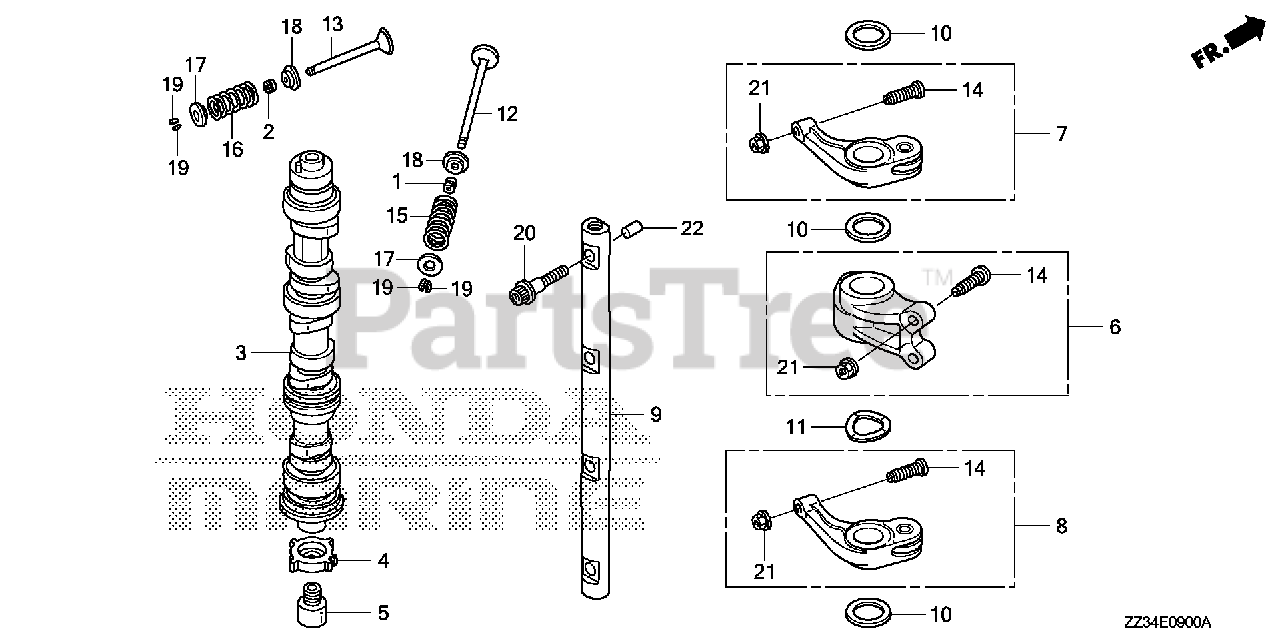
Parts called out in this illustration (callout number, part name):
1	SEAL A, VALVE STEM (NOK)
2	SEAL B, VALVE STEM (NOK)
4	PLATE, TDC PULSER
5	BOLT, TDC PULSER PLATE
6	ARM, IN. VALVE ROCKER
7	ARM A, EX. ROCKER
8	ARM B, EX. ROCKER
9	SHAFT, ROCKER
10	WASHER, THRUST
11	WASHER, IN. WAVE
12	VALVE, IN.
13	VALVE, EX.
14	SCREW, TAPPET ADJUSTING
15	SPRING, IN. VALVE
16	SPRING, EX. VALVE
17	RETAINER, VALVE SPRING
18	SEAT, VALVE SPRING
19	COTTER, VALVE (FUJI VALVE)
20	BOLT, ROCKER ARM SHAFT
21	NUT, TAPPET ADJUSTING (TOKAI TRW)
22	ROLLER (4X8)
